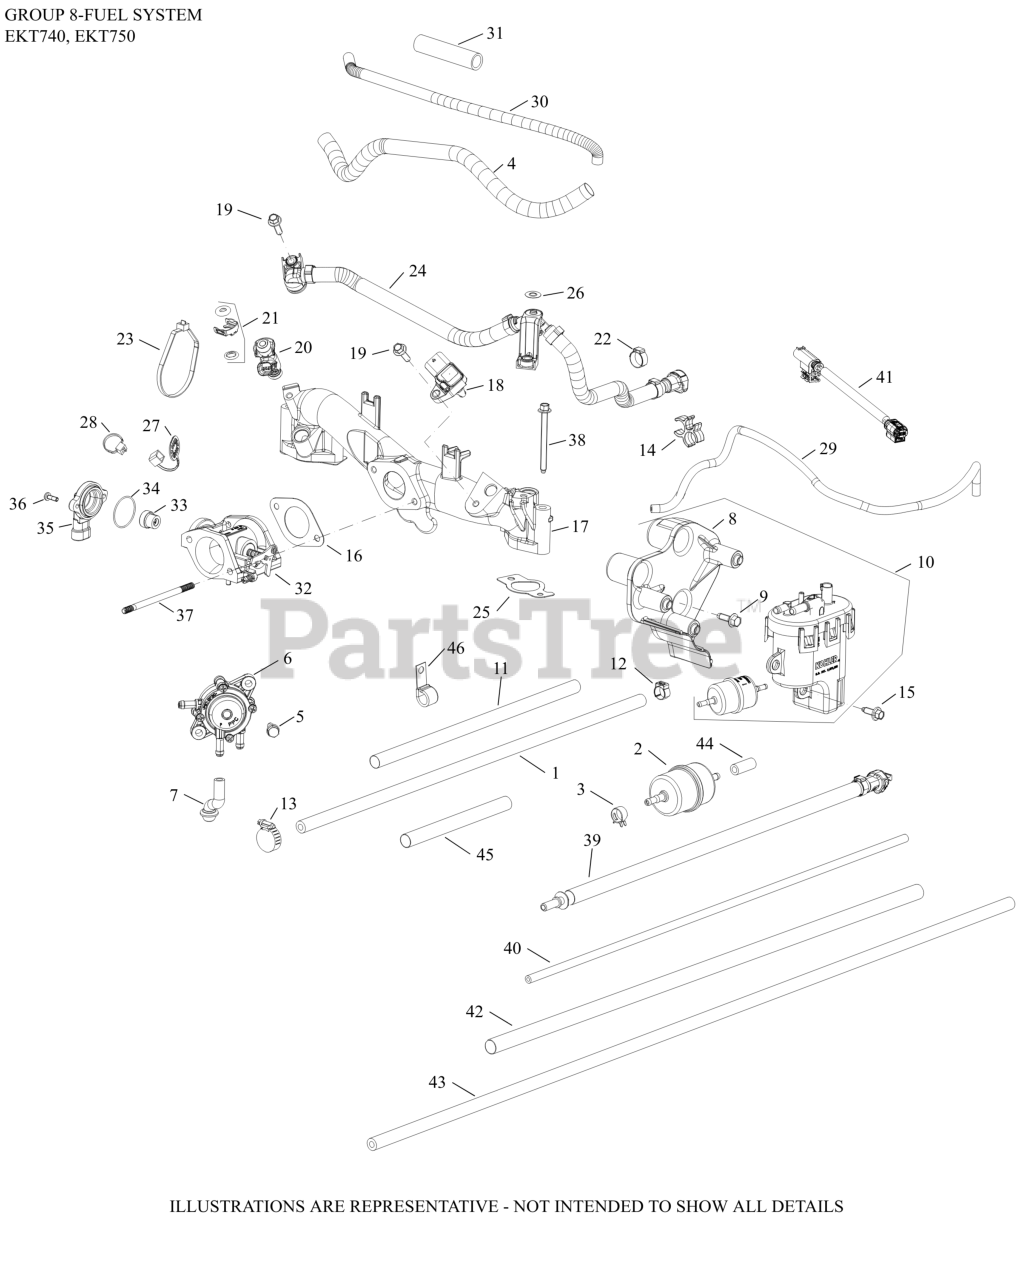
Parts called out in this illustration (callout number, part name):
1	HOSE,LW PERM.FUEL 24.00"-USE 25 111 81-S
2	FILTER, FUEL
3	SPRING CLAMP, HOSE
4	SLEEVE, ANTI ABRASION
5	SCREW, TAP M6X1.7X18
6	PUMP, FUEL (PULSE)-(#2539326S)
7	HOSE, PULSE PUMP(STEEL COVERS)
8	BAFFLE, FUEL MODULE
9	SCREW, THREAD FORMING
10	FUEL PUMP
10	KIT, FPM W/BRCKT(EKT740-750, EZT715-750)
11	SLEEVE, INSULATING
12	CLAMP, OETIKER
13	CLAMP, HOSE (KM)-USE 25 237 31-S
14	RETAINER, HOSE
15	SCREW, HEX FLANGE (M6 W/DOG POINT)
16	GASKET, THROTTLE BODY
17	MANIFOLD MACHINED (EFI)
18	SENSOR, T-MAP
19	SCREW, FLG M6x1.0x20
20	INJECTOR, FUEL
21	KIT, FUEL INJECTOR O-RING
22	CLAMP, HOSE
24	FUEL HOSE ASSY(ECV,FCV,EZT,EKT,PCH,PCV)
25	KIT, INTAKE MANIFOLD GASKET
26	CLIP, RETAINER
27	CAP, CONNECTOR
28	TIE, CABLE
30	SLEEVE, ANTI-ABRASION
31	SLEEVE, CORRUGATED
32	BODY ASSEMBLY, THROTTLE W/TPS & TS
33	MAGNET, TPS SENSOR
34	O-RING, TPS SENSOR
35	SENSOR, THROTTLE POSITION
38	SCREW, HEX FLANGE (M6 W/DOG POINT)
